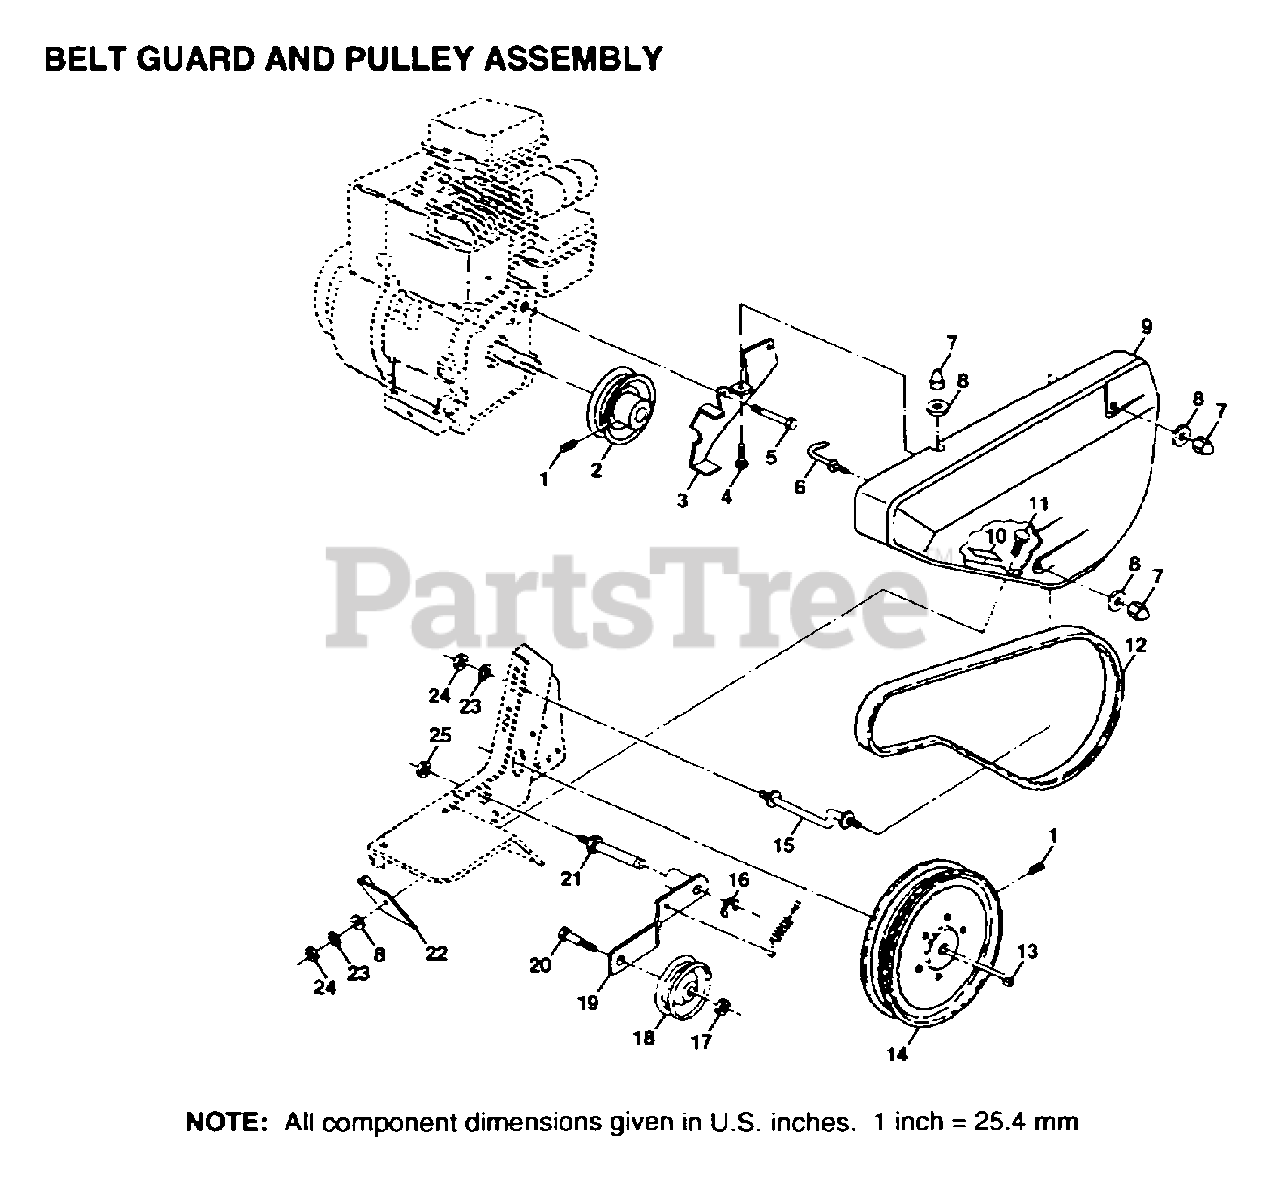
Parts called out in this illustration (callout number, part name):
1	SET SCREW
4	BOLT
7	NUT-CAP TI
8	WASHER
10	PAD IDLER TI
11	BOLT T
13	KEY T
14	TRANS SHEAVE RT
16	KLIP RING TI
17	NUT
19	IDLER ARM TI
21	SHAFT IDLER TI
22	SHIELD-DIRT TI
23	LOCKWASHER
25	JAM NUT TI
